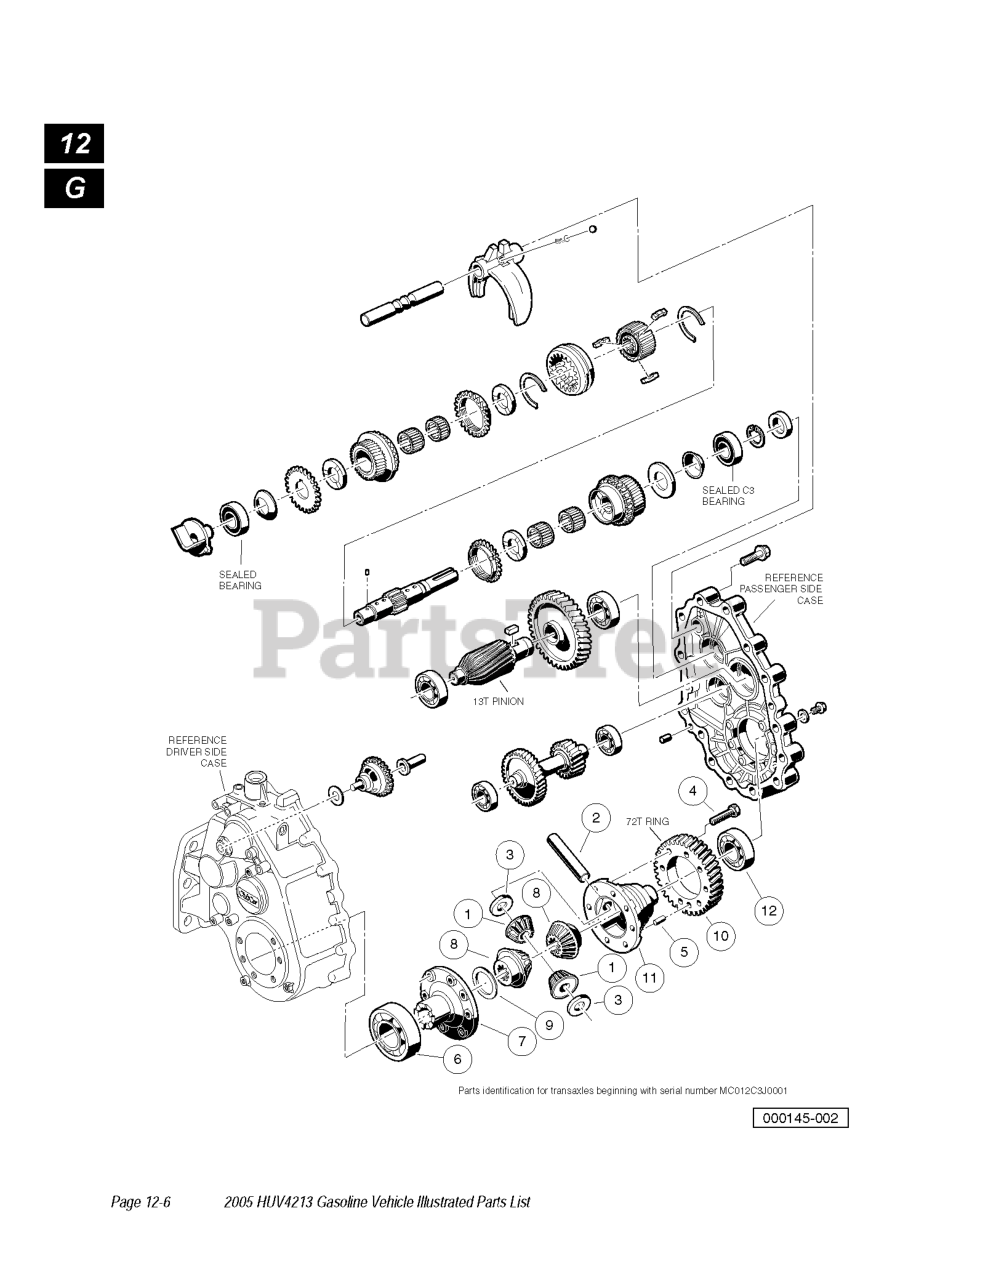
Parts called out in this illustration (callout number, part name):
1	DIFFERENTIAL IDLER GEAR
2	DIFFERENTIAL PIN
3	PLATE
4	SCREW, M8-1.25 X 35MM HEX HEAD
5	PIN, DOWEL
6	BEARING, AXLE TUBE RIGHT
7	CASE - GEAR LH
8	GEAR - BEVEL, SIDE 16T
9	PLATE-THRUST
10	GEAR, HELICAL, RING, 72T
11	CASE, 72T DIFF GEAR CARRIER
12	INNER AXLE, TUBE BEARING
